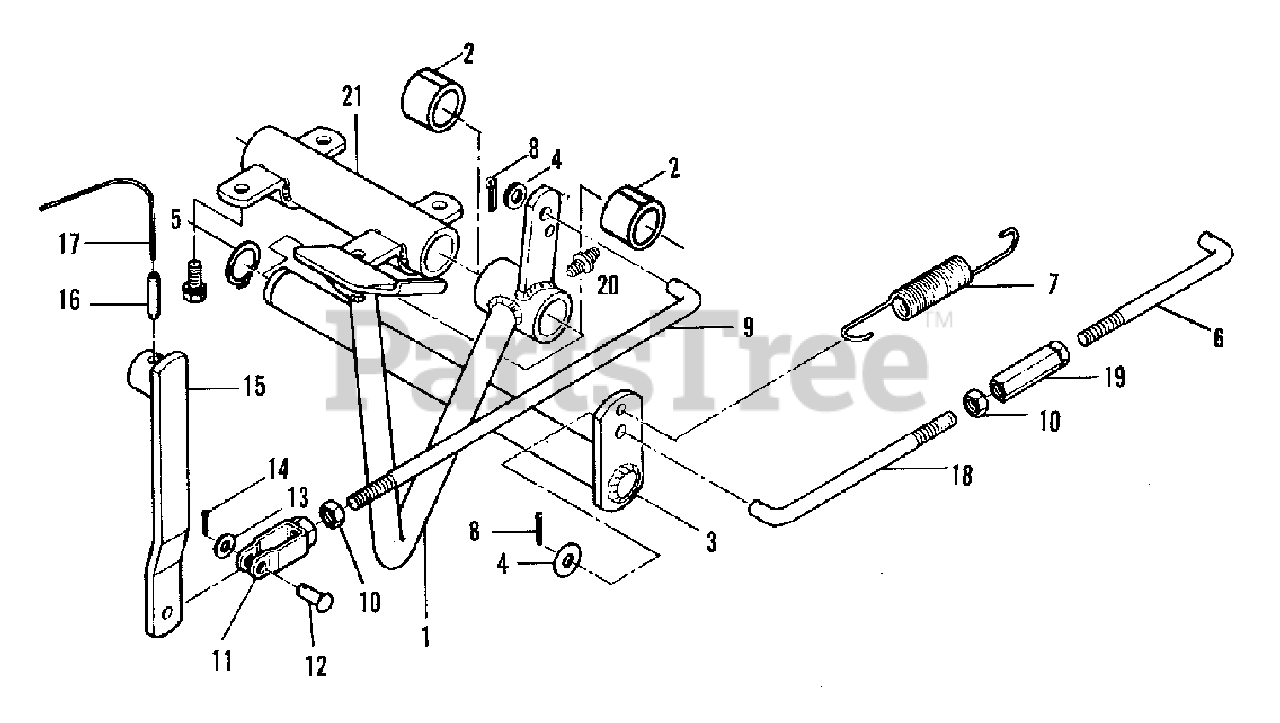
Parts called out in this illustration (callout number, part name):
1	PEDAL, clutch
5	RING, M25 snap
6	ROD, ®, brake
7	SPRING, pedal return
8	PIN, cotter
9	ROD, clutch
11	CLEVIS, clutch rod
14	PIN, cotter
15	LEVER, clutch
16	PIN, M8 x 32 roll
18	ROD (F), brake
19	TURNBUCKLE
20	FITTING LUBE
